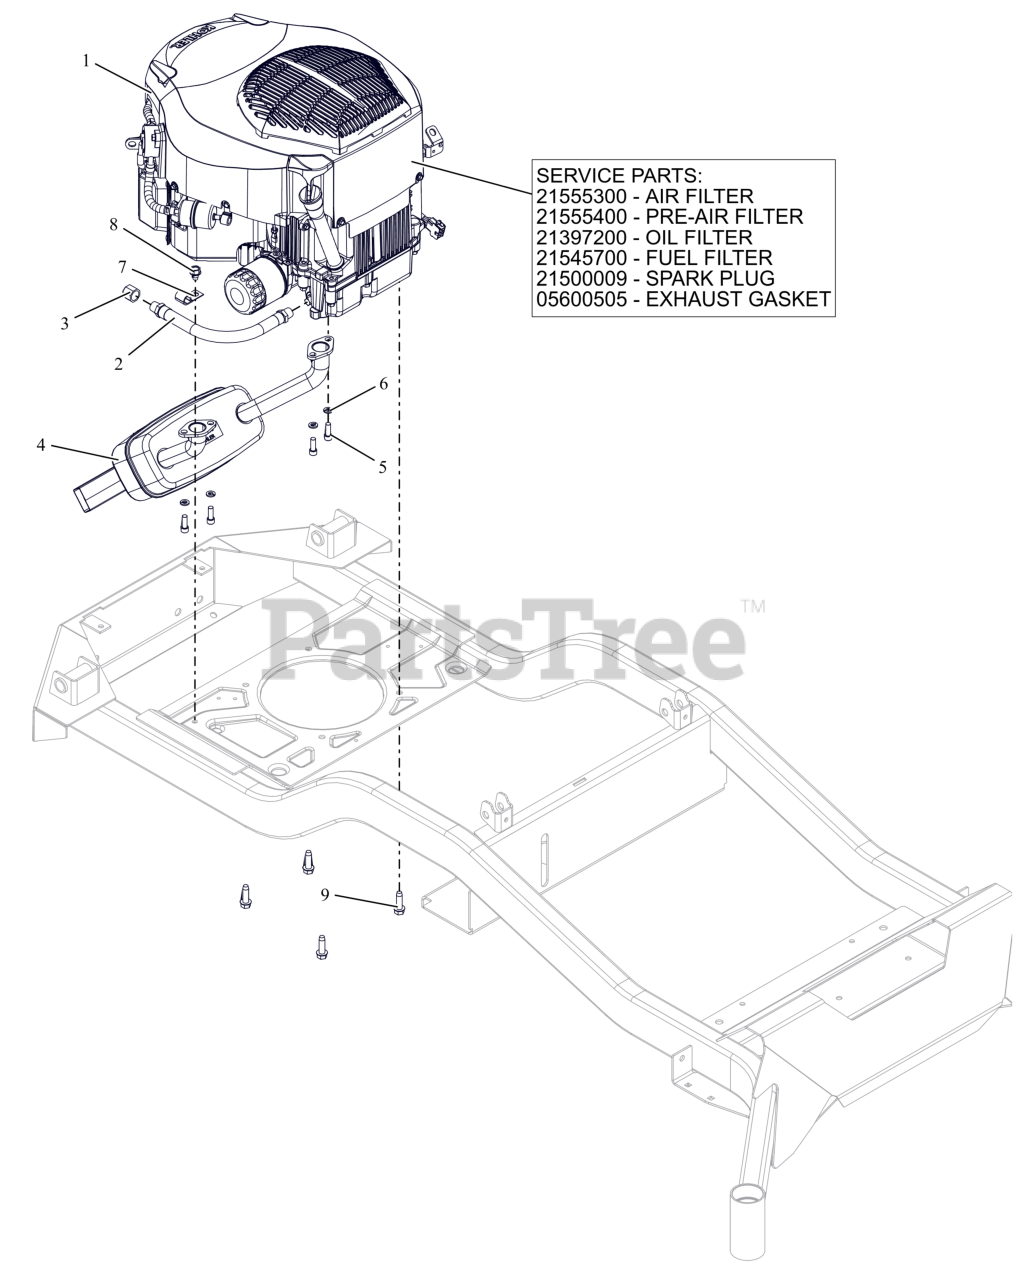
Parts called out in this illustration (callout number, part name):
1	ENGINE, KOHLER - KT740
1	AIR FILTER, KOHLER
1	PRE CLEANER, KOHLER
1	FILTER, OIL - KOH CV20
1	FILTER-FUEL KOHLER COURAGE PRO
1	PLUG, SPARK KOHLER
1	GASKET, MUFFLER COURAGE TWIN
2	HOSE,HYD .38-11-0K M6NO-M6N0
3	PIPE CAP 3/8 NPT FEMALE
4	MUFFLER, KOHLER
5	SCR-CAP .31-18X.88 S/HD G8 ZCC
6	WSHR,LK-REG .312X.078 ZCC
7	J-CLAMP
8	SCR,TAP .375-16X.50 HWH TR ZCC
9	SCR,TAP .375-16X1.25HWH TR ZCC
